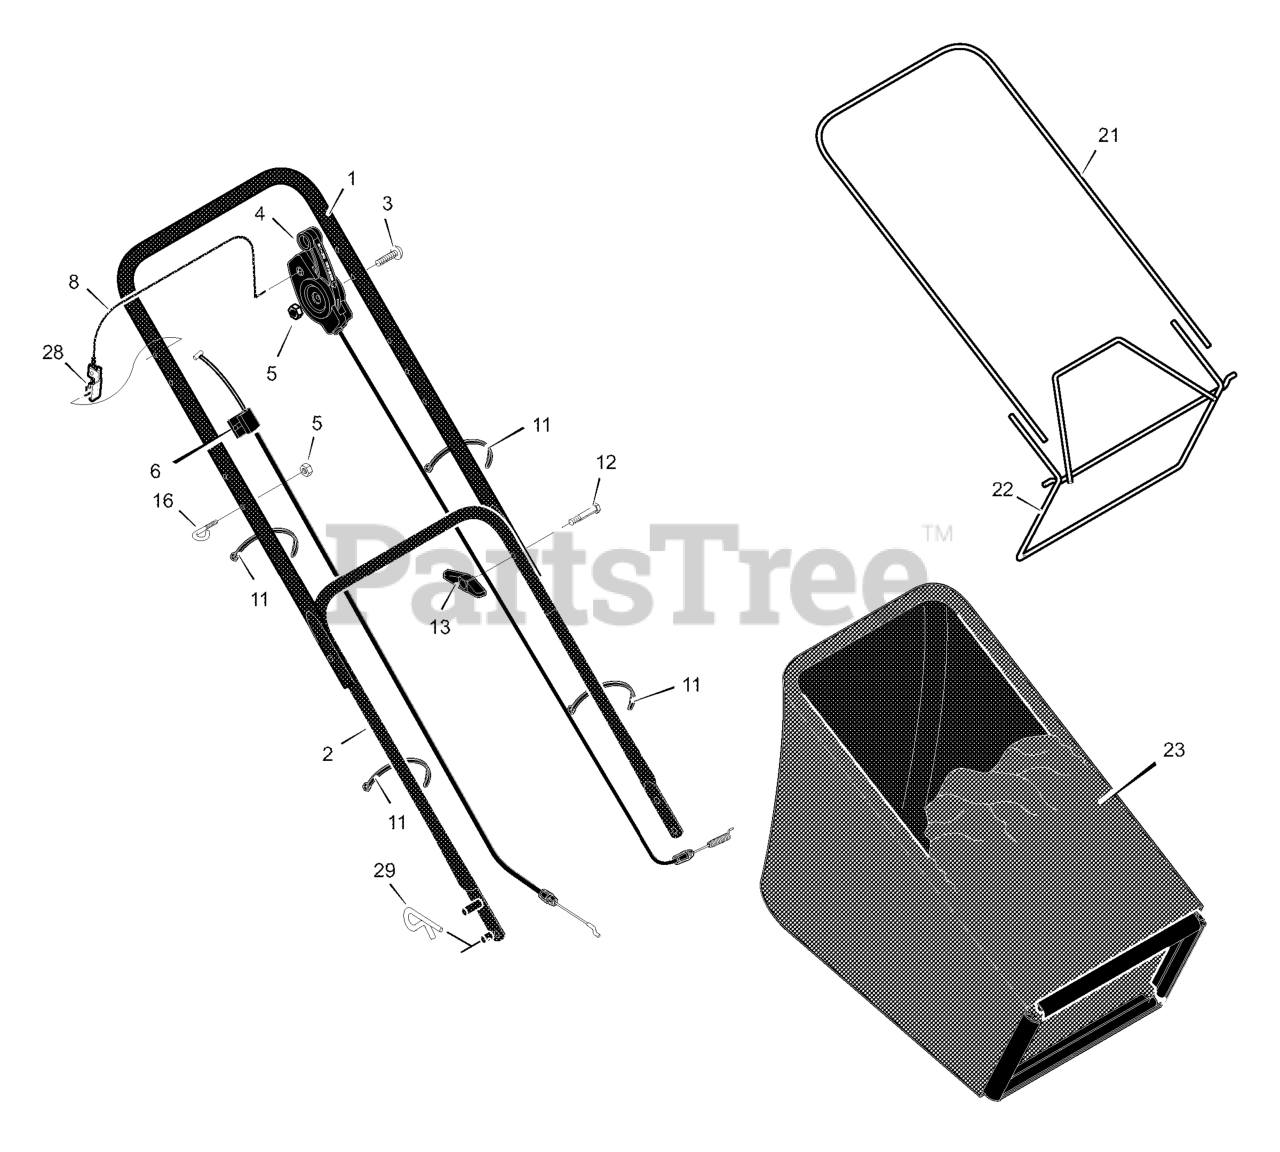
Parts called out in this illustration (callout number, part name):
1	Handle, Upper
2	Handle, Lower
4	Control, Drive
5	Locknut
6	Cable, Stop
8	Engine Stop Lever
11	Fastener, Cable
13	Knob
16	Guide, Rope
21	Frame, Top
22	Frame Assembly
23	Bag, Cloth
28	Bracket, Stop Lever
29	Pin, Hair
